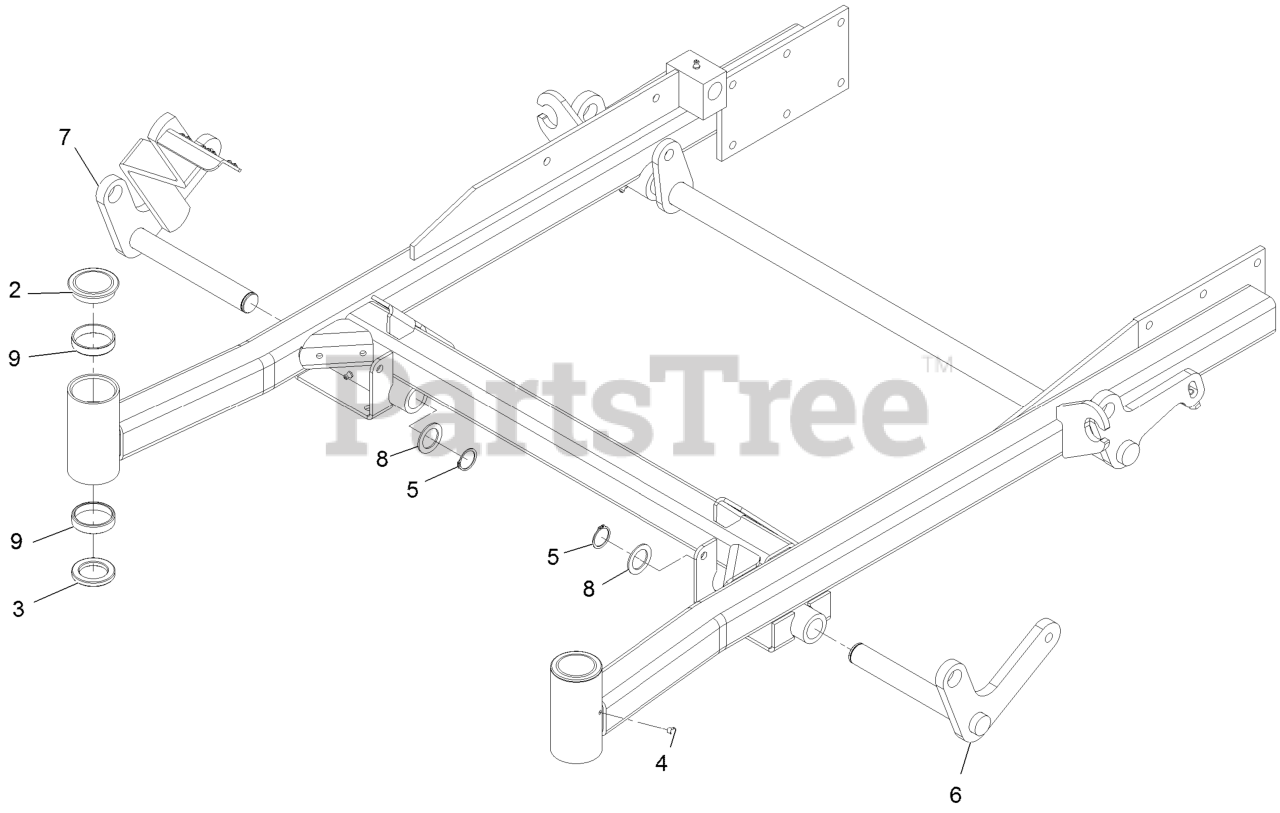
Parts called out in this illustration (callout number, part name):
2	CAP-GREASE
3	SEAL-GREASE
5	RING-RETAINING
6	WLD,FRONT LIFT SHAFT-LH
7	WLD,FRONT LIFT W/LEVER
8	WASHER-SPACER
9	CUP-BEARING
